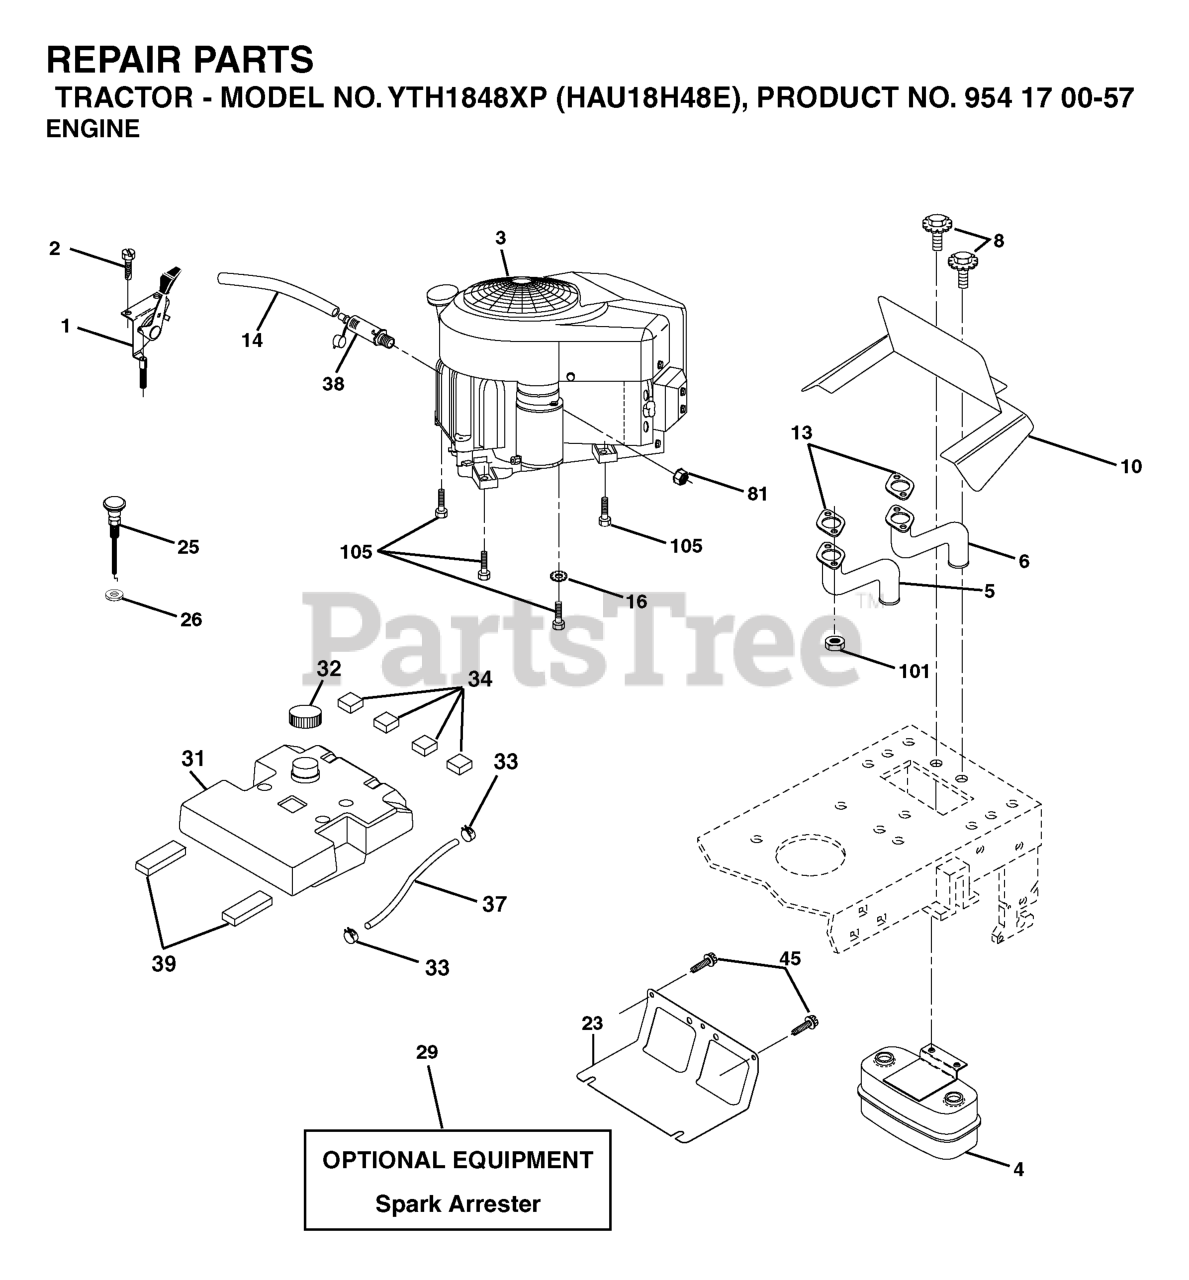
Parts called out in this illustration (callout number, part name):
1	CONTROL, THROTTLE
2	SCREW
4	MUFFLER.TWIN.CYL.LOW.TONE
5	EXHAUST.TUBE.LH.KAWASAKI.
6	EXHAUST.TUBE.RH.KAWASAKI.
8	BOLT.5/16-18UNCX3/4 W/SEMS.BLK
10	RP SHIELD HEAT MUFFLER
14	TUBE, DRAIN OIL ASM.
16	LOCKWASHER
23	SHIELD.BROWNING.DBR.GUARD
25	CHOKE CONTROL
26	Nut Keps 3/8 - 24 UNF
29	KIT.SPARK ARRESTOR 794945 B&S
31	TANK.FUEL(3.5.GAL)
32	FUEL CAP
33	HOSE CLAMP
34	PAD-SPACER LT
37	REPL BY 532 00 85-43
39	PAD IDLER TI
45	SCREW, 3/8-16X3/4
81	NUT
101	FLANGE NUT
105	SCREW 3/8-16X1
